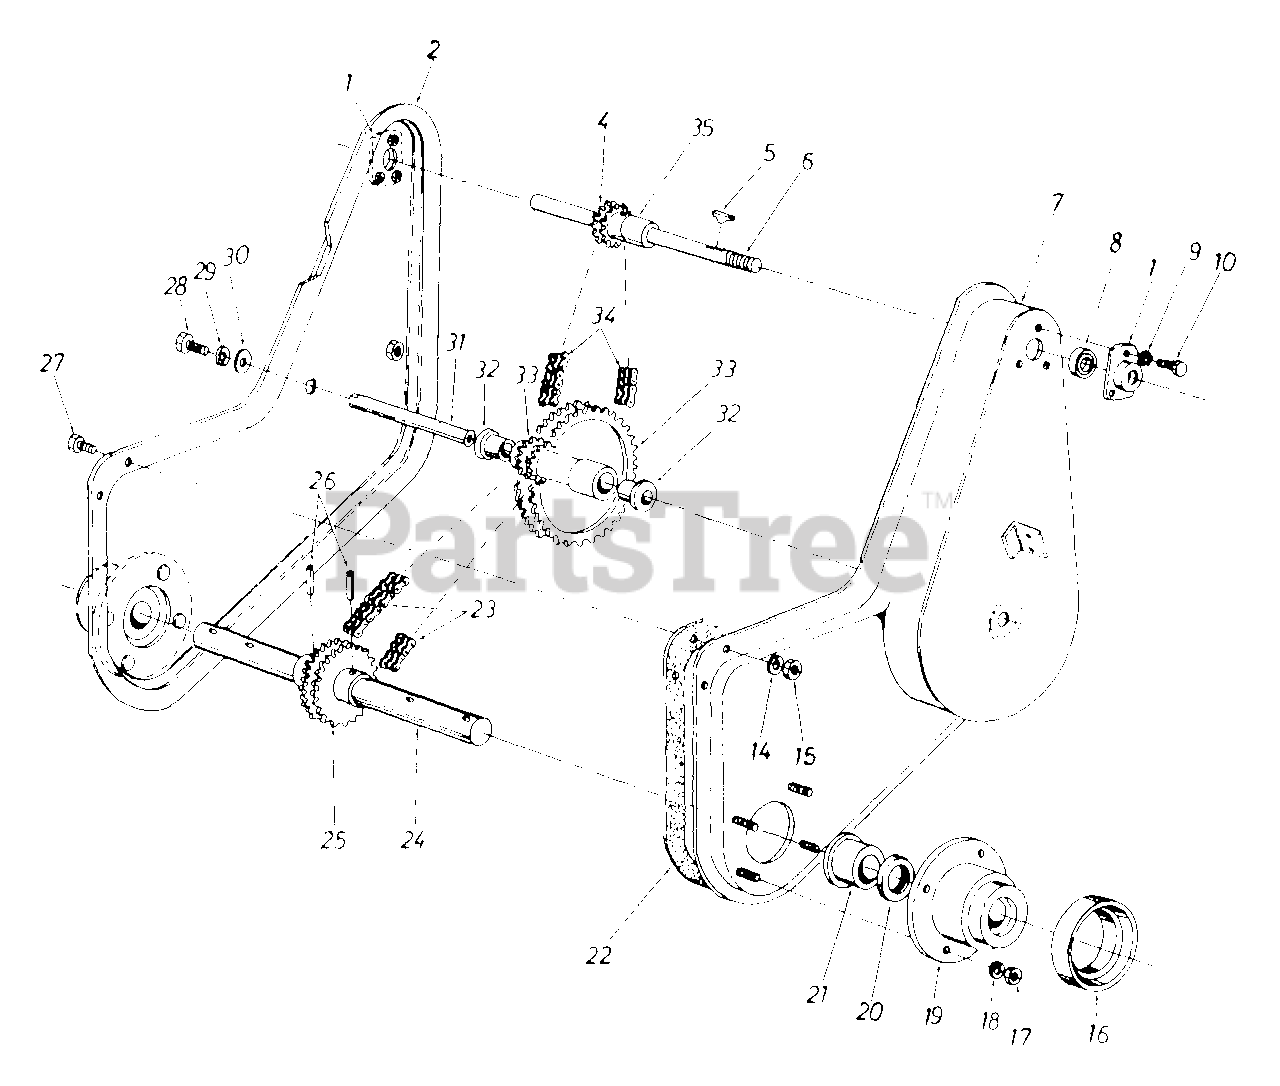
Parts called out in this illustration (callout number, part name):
2	Housing Assembly - R.H.
5	#6 Hi-Pro Key 5/32" x .62" Lg.
6	Input Shaft Assembly
9	L-Wash. 1/4" I.D.
10	Hex Bolt 1/4-20 x .62" Lg.
14	L-Wash. 1/4" I.D.
15	Hex Cent. L-Nut 1/4-20 Thd.
16	Dust Cap Cover
17	Hex Cent. L-Nut 5/16-18 Thd.
18	L-Wash. 5/16" I.D.
19	Cast Bearing Housing
20	Oil Seal
21	Flange Bearing 1.25" I.D. x 1.75" O.D.
22	Gasket
23	Roller Chain #40-2 x 34.0" Lg.
24	Tine Shaft
25	Double Sprocket T24-2 Teeth 1/2" Pitch
26	Spiral Pin 3/8" Dia. x 2.00" Lg.
27	Hex Bolt 1/4-20 x .62" Lg.
28	Hex Bolt 5/16-18 x .75" Lg.
29	L-Wash. 5/16" I.D.
30	Fl-Wash. 5/16" I.D.
31	Sprocket Shaft
32	Flange Bearing .62" I.D. x .75" O.D.
33	Double Sprocket Assembly
34	Roller Chain #35-2 x 36.75" Lg.
35	Spacer 5/8" I.D. x 7/8" O.D.
